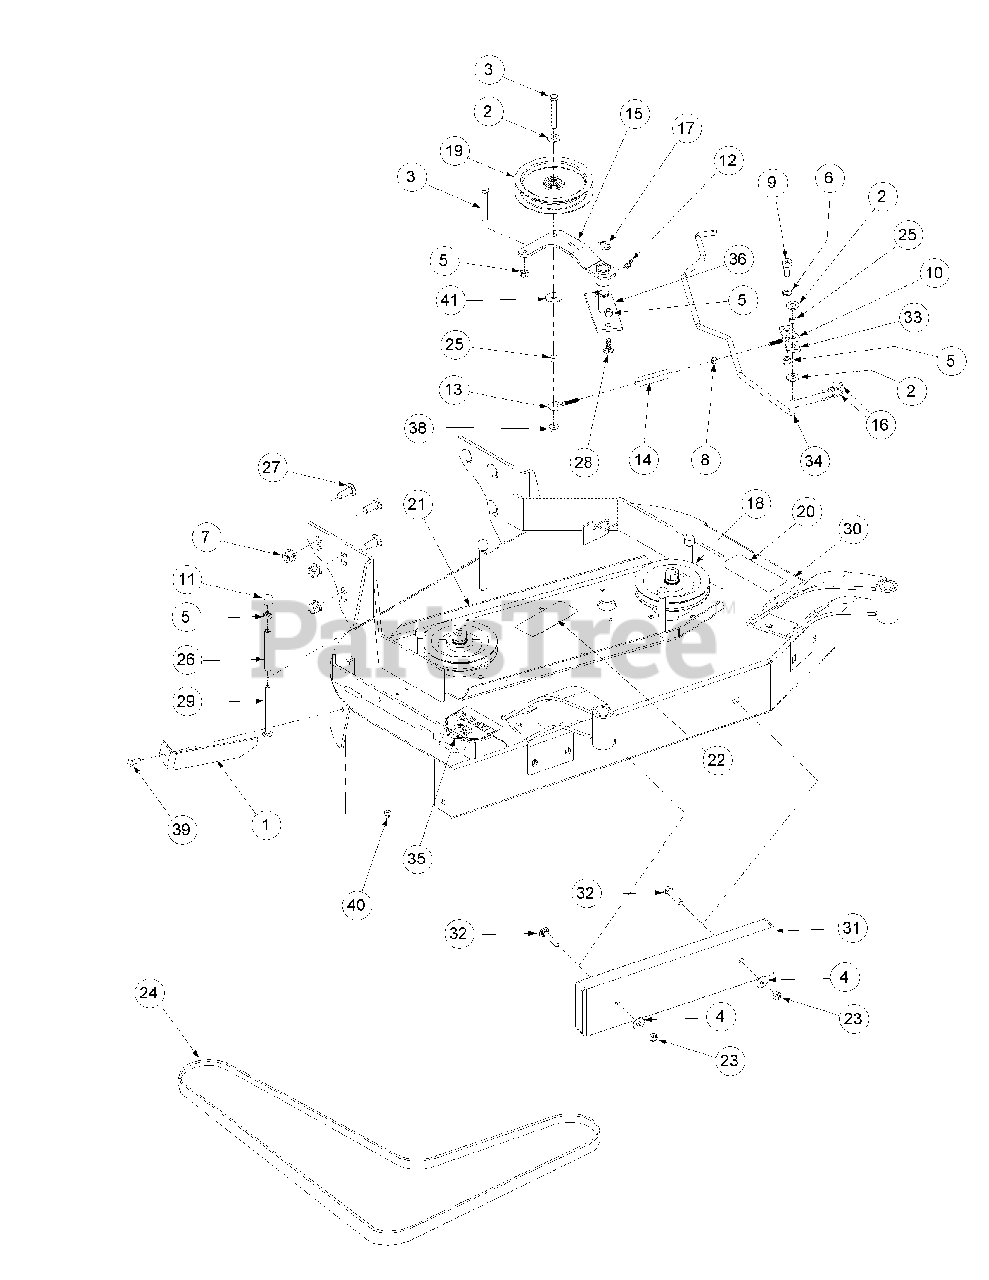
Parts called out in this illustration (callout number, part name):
1	Baffle, Deck Chute
2	Flat Washer, 3/8 Zinc
3	Hex Cap Screw, 3/8-16 x 2.75
4	Flat Washer, 3/8 Zinc
5	Lock Nut, Nylon Insert, 3/8-16
6	Shim Washer
7	Nut, Flange Lock, 1/2-13
8	Hex Nut, 5/16-18
9	Shoulder Bolt
10	Eye Bolt, Right Hand
11	Cap, Black Vinyl
12	Grease Fitting, 45 degree, 1/4-28
13	Eye Bolt, Left Hand
14	Turnbuckle
15	Idler Arm
16	Hair Pin, 3/8"-1/2"
17	E-Ring, Retainer
18	Pulley Deck
19	Idler Deck Take-up
20	Decal Rotating Blade
21	Deck Stiffener
22	Decal, Warning Shield Missing
23	Lock Nut, 3/8-16
24	Belt Drive
25	Turnbuckle, Sleeve
26	Spacer, Belt Guide
27	Carriage Bolt, 1/2-13 x 1-1/4
28	Carriage Bolt, 3/8-16 x 1
29	Carriage Bolt, 3/8-16 x 4.5
32	Carriage Bolt, 3/8-16 x 1-1/2
34	Rod Clutch Link
35	Decal, Danger Hands and Feet
36	Idler Base
37	Lubricant Grease
38	Nut, Hex Flange Lock, 3/8-16
39	Hex Cap Screw, 5/16-18 x .75
40	Nut, Hex Flange Lock, 5/16-18
41	Washer, 1.25 x .411 x .100
